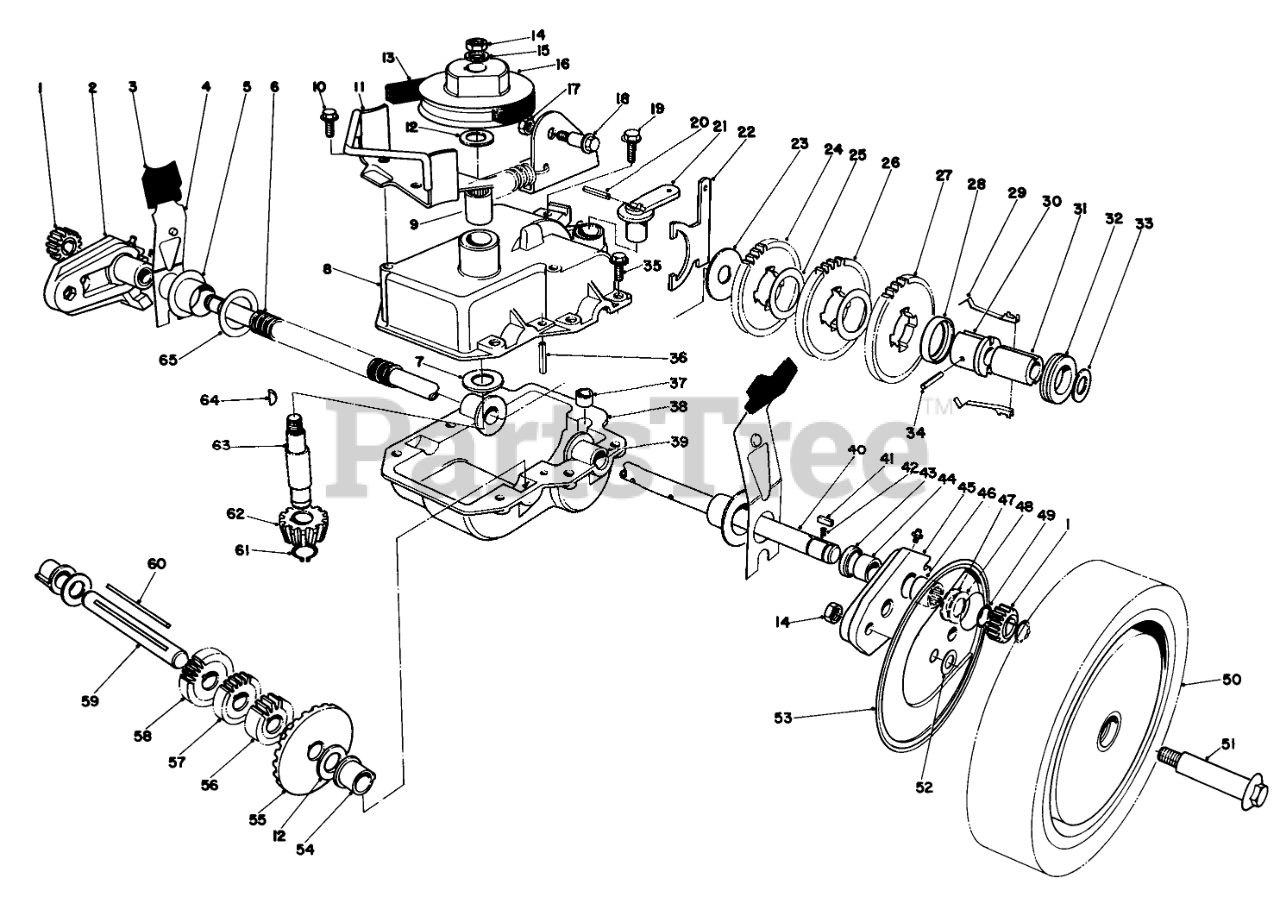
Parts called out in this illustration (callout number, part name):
1	GEAR-PINION
2	Pivot Arm R.H. (Incl. Ref. #43, 44 & 46)
3	KNOB-ARM
4	SPRING ARM ASM SP
5	CAP-END
6	CONDUIT-CONVOLUTED, SPLIT
7	Thrust Washer
8	Case-Upper
9	Bearing
10	SCREW
11	Belt Guide Bracket
12	WASHER-THRUST
13	V-BELT
14	Nut
15	WASHER-FLAT
16	PULLEY
17	NUT-LOCK, CONE
18	SHOULDER BOLT
19	SCREW-HWHTF
20	PIN-COIL
21	LEVER-SHIFT
22	Shift Yoke
23	WASHER
24	GEAR-38T
25	WASHER
26	Gear-40 Tooth
27	GEAR-42T
28	KEY RETAINER
29	Key
30	Body-Sleeve
31	SLEEVE
32	COLLAR-SHIFT
33	WASHER-PLAIN
34	PIN-SPRING
35	SCREW-HWH, THREAD ROLL
36	ROLL PIN 3/16 X 1 IN
37	BUSHING-YOKE
38	LOWER GEAR CASE CAST
39	Bushing
40	Output Shaft
41	KEY RECTANGULAR
42	SPRING-COMPRESSION
43	Seal
44	Bushing
45	Pivot Arm L.H. (Incl. Ref. #43, 44 & 46)
46	Needle Baring
47	Washer
48	THRUST WASHER
49	RING-RETAINING
50	Wheel & Tire Assy.
51	BOLT-WHEEL
52	WASHER
53	WHEEL COVER
54	Botching Shaft
55	BEVEL GEAR
56	14 T GEAR
57	16 T GEAR
58	GEAR-18T
59	Sort Shaft
60	Key Square
61	RING-RETAINING
62	PINION-BEVEL
63	INPUT SHAFT
64	KEY-WOODRUFF
65	Washer
